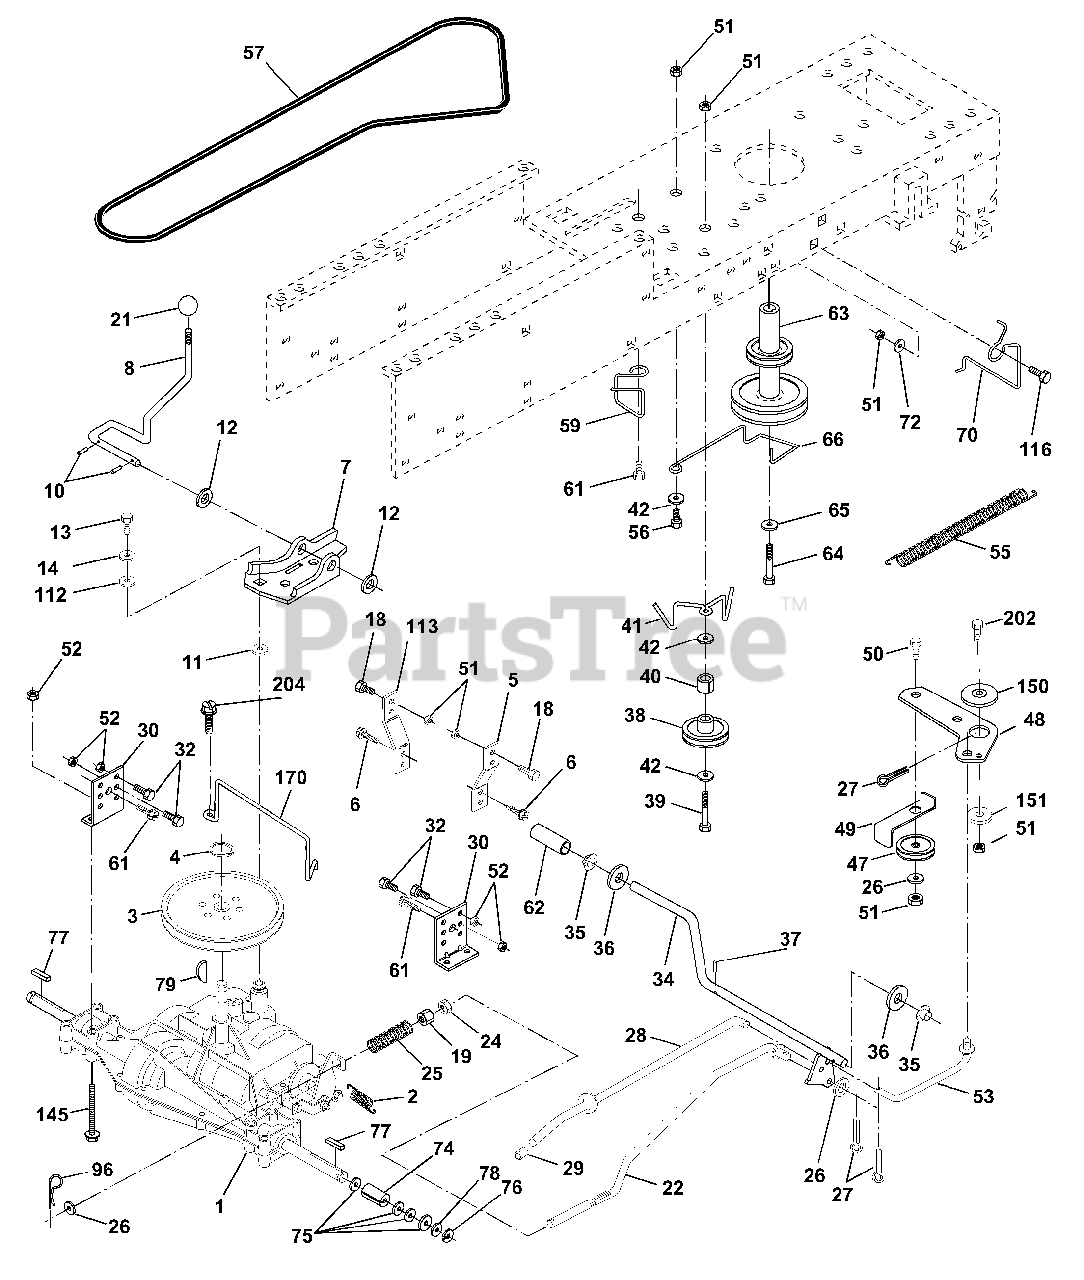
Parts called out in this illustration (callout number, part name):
2	Spring Return Brake
3	Pulley Transaxle 18" tires
4	Ring Retainer # 5100-62
5	Strap Torque 30 Degrees RH
6	Screw 5/16-18 x 3/4
7	Plate Rod Shift T/a
8	Rod Shifter Blk
10	Pin Cotter 1/8 X 1 Cad
11	Washer Plate Shf 388 Sq Hole
12	Washer 15/32 X 3/4 X 16 Ga
13	Bolt 1/4-28 unf Gr. 8 w/Patch
14	Washer Lock Hvy Helical 1/4
18	Bolt Fin Hex 3/8-16unc X 1 Gr. 5
19	Nut lock Hex w/Ins 3/8-16 Unc
21	Knob Rd 1/2-13 Plstc Thds Blk
22	Rod Brake LT
24	Nut Hex Jam 3/8-16 Unc
25	Spring Rod Brake 2 00 Zinc
26	Washer 13/32 X 13/16 X 16 Ga
27	Pin Cotter 1/8 X 3/4 Cad
28	Rod Brake Parking LT/YT
29	Cap Brake Parking Black
30	Bracket Transmission
32	Bolt Fin Hex 5/16-18 x 3/4
34	Shaft Asm Pedal Foot
35	Bearing Nylon Blk 629 Id
36	Washer 21/32 X 1 X 16 Ga
37	Pin Roll 3/16 X 1"
38	Pulley Idler Flat
39	Bolt Rdhd 3/8-16 Unc x 2-3/4 Gr.5
40	Spacer Split 395 X 59 Bzp
41	Keeper Belt Idler
42	Washer 13/32 X 13/16 X 12 Ga
47	Pulley Idler V Groove Plastic
48	Bellcrank Clutch Grnd Drv STL
49	Retainer Belt Style Spring
50	Bolt Hex Hd 3/8-16unc X 1-1/2
51	Nut Crownlock 3/8-16 Unc
52	Nut Crownlock 5/16-18 unc
53	Link Clutch 7 66
55	Spring Return Clutch 6 75
56	Bolt Fin Hex 3/8 X 16 x 1-1/4
57	V-Belt Ground Drive 95
58	Keeper Belt RH LT Pnt/zinc 16g
59	Keeper Belt Chassis Span Ctr
61	Screw 3/8-16 x 3/4
62	Cover Pedal Blk Round
63	Engine Pulley LT/YT
64	Bolt Hex 7/16-20x4 Gr 5
65	Washer Lock Hvy Hlcl Spr 7/16
66	Keeper Belt Engine
70	Guide Belt Mower Drive RH
72	Washer 13/32 X 1-1/4 X 12 Ga
74	Spacer Axle
75	Washer 25/32 X 1 1/4 X 16 Ga
76	E-ring #5133-75
77	Key Square 2 0 X 1845/ 1865
78	Washer 25/32 X 1-5/8 X 16 Ga
79	Key Woodruff
96	Retainer Spring 1"
112	Washer 9/32 X 3/4 X 10 Ga
113	Strap Torque 90 Degrees LH
116	Bolt Rdhd Sq Neck 3/8-16 x 1.25
145	Bolt Hex Flg.Hd. 5/16-18 x Gr.5
150	Bushing Bellcrank
151	Washer 13/32 x 2 x 10 Ga.
202	Bolt Carr Sh 3/8-16 x 1-1/2 Gr.5
204	Screw 5/16-18 x 1
